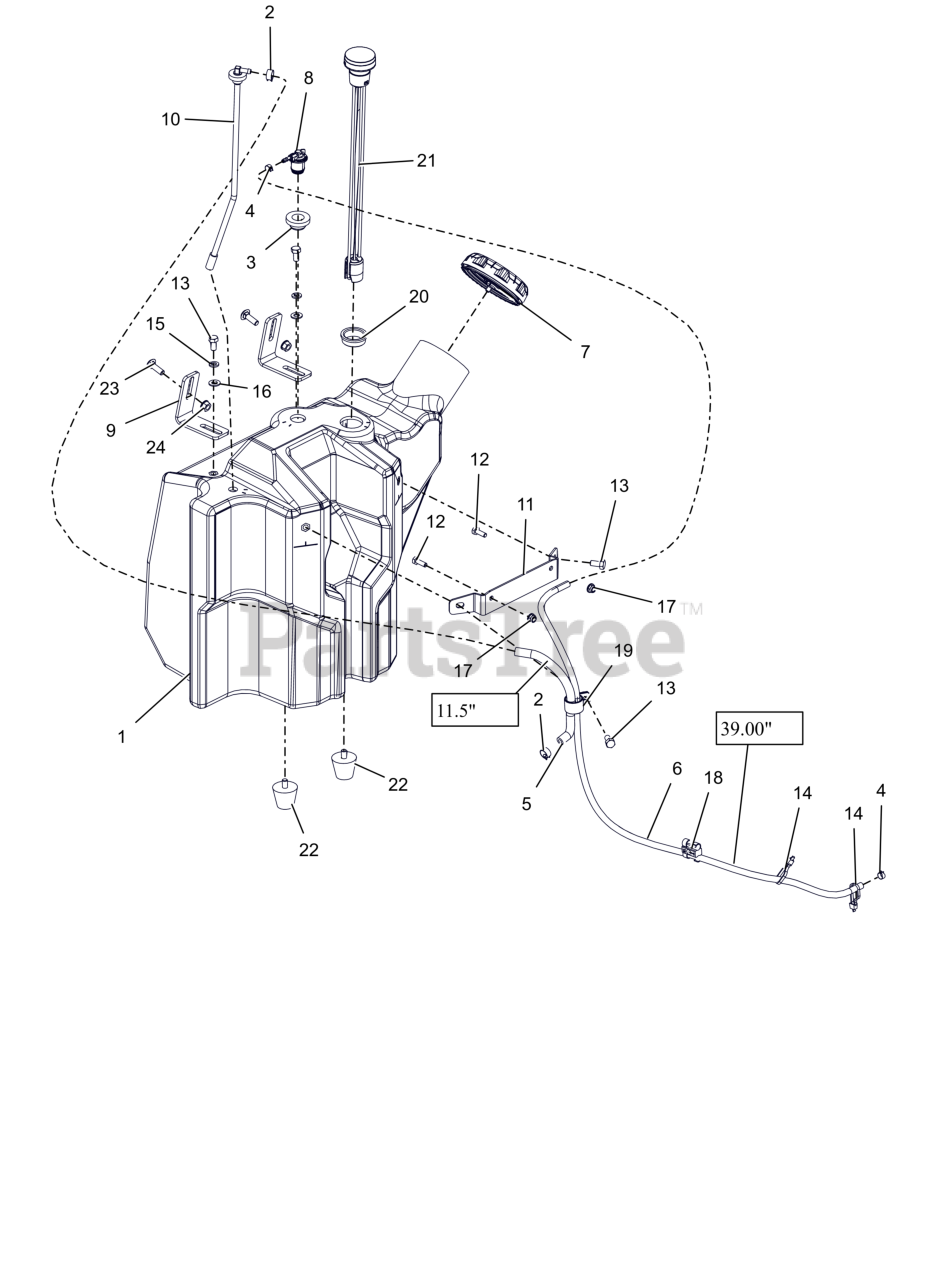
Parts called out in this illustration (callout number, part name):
1	ASM, 32-36" PROSTANCE FUEL TANK
2	CLAMP, FUEL LINE
3	GROMMET, REMOTE VENT NITRILE
4	CLAMP-HOSE, SPRING .188
5	HOSE, .25 LOW-PERM BULK GAS
6	HOSE, .188 LOW-PERM BULK GAS
7	CAP, FUEL VENTIN AUTOLOCK
8	VALVE, COMBINATION VENT 3/16
9	BRKT, TANK HOLDDOWN
10	ASM, PROSTANCE FUEL LINE PICK-UP
11	BRKT, OVERFLOW MTG (BLACK)
12	BLT, HEX .25-20X.75 G5 ZCC
13	BLT, HEX .31-18X.625 G5 ZCC
14	CABLE TIE, .15 X 8.50
15	WSHR,LK-REG .312X.078 ZCC
16	WSHR,FLT .344X.688X.065 ZCC
17	NUT,NYL-FLG .25-20 GF ZCC
18	CLIP, T, .38-.50
19	CLAMP, COUSHIONED STEEL REV
20	GROMMET, FUEL GAUGE
21	GAUGE, REMOTE FUEL SEALED 15"
22	BUMPER, STUD MOUNTED CONE SHAPED
23	BLT,RHSN .31-18X1.00 G5 ZCC
24	NUT,LK-CTR-FLG .31-18 GF ZCC
